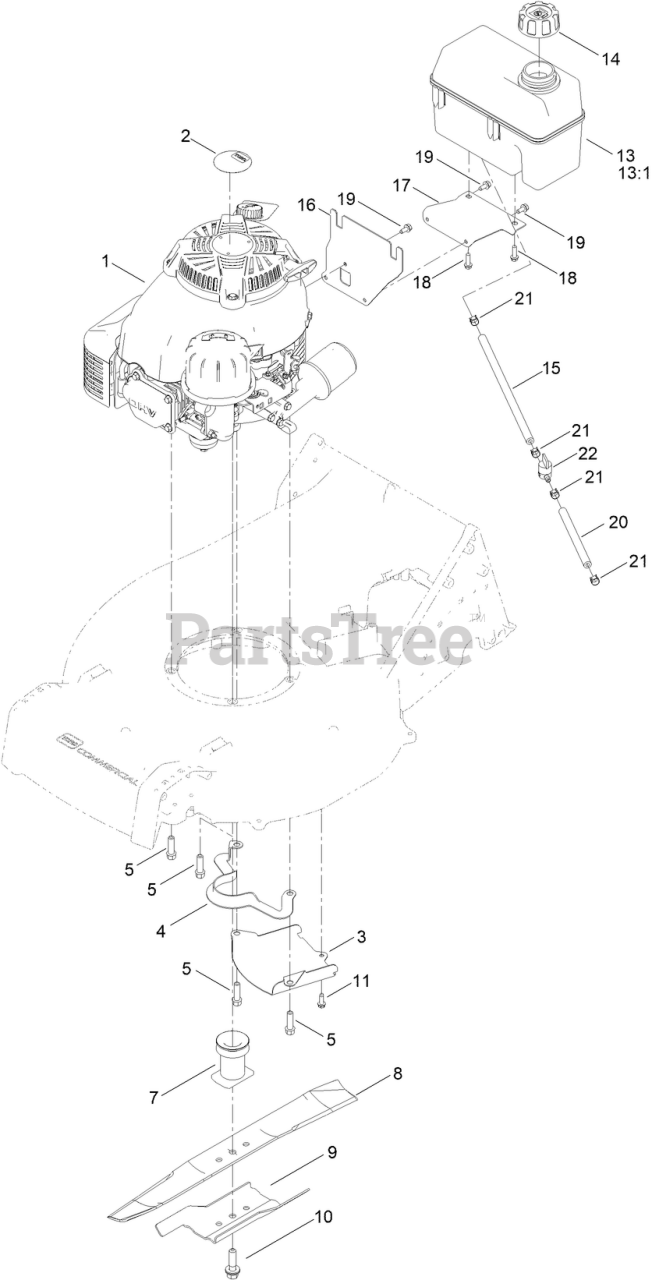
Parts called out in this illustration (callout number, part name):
3	SHIELD-GRASS
4	GUIDE-BELT
5	SCREW-TAPTITE
7	DRIVER-BLADE
8	BLADE-21IN, RECYCLING
9	ACCELERATOR-BLADE
10	BOLT-BLADE
11	SCREW-HWHTF
13	TANK-FUEL
13:1	FITTING-PLASTIC
14	CAP-GAS
15	HOSE-FUEL
16	BRACKET-TANK, MOUNTING
17	BRACKET-TANK, SUPPORT
18	SCREW-HWH
19	SCREW-HWH
20	HOSE-FUEL
21	CLAMP-HOSE
22	VALVE-FUEL
